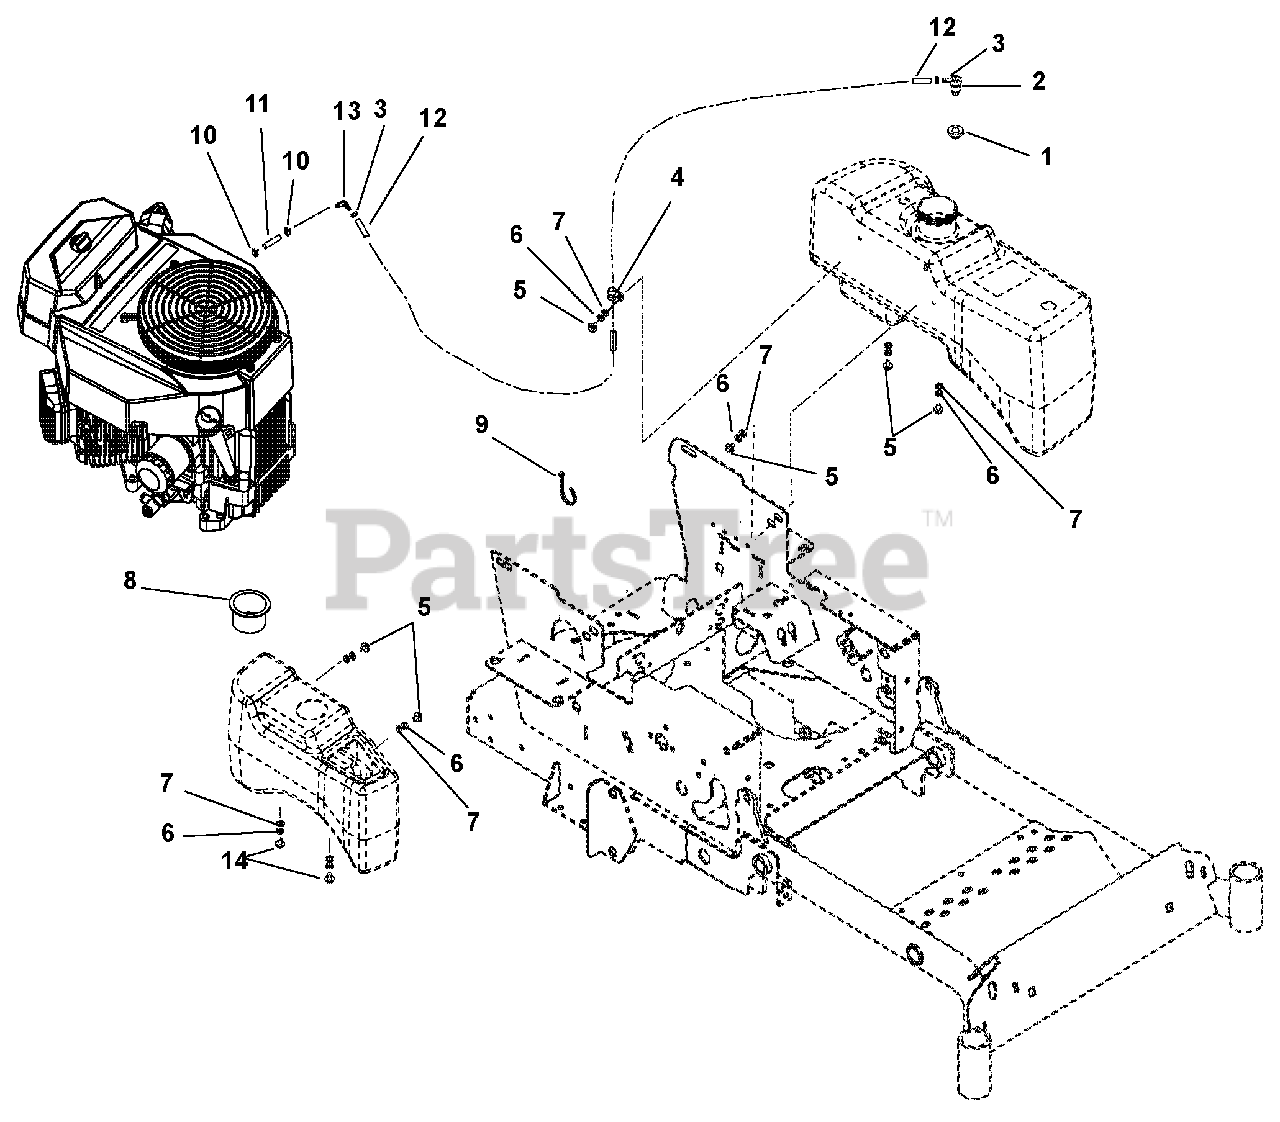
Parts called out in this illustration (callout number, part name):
2	Valve
3	Hose, Clamp
5	Bolt, .31-18 x .62
6	Washer, Locking .31 x .078 Regular
7	Washer, Flat Steel .38 x .875 x .083
8	Cupholder, Snap-in 3.75 O.D.
9	Tie, Cable LG 5.50
10	Clamp, Spring .188
11	Hose, Fuel .18"
12	Hose, Fuel .25"
13	Fitting, 90° Vacuum .18 x .25
14	Screw, Plastite .25-10 x .75 YZ
